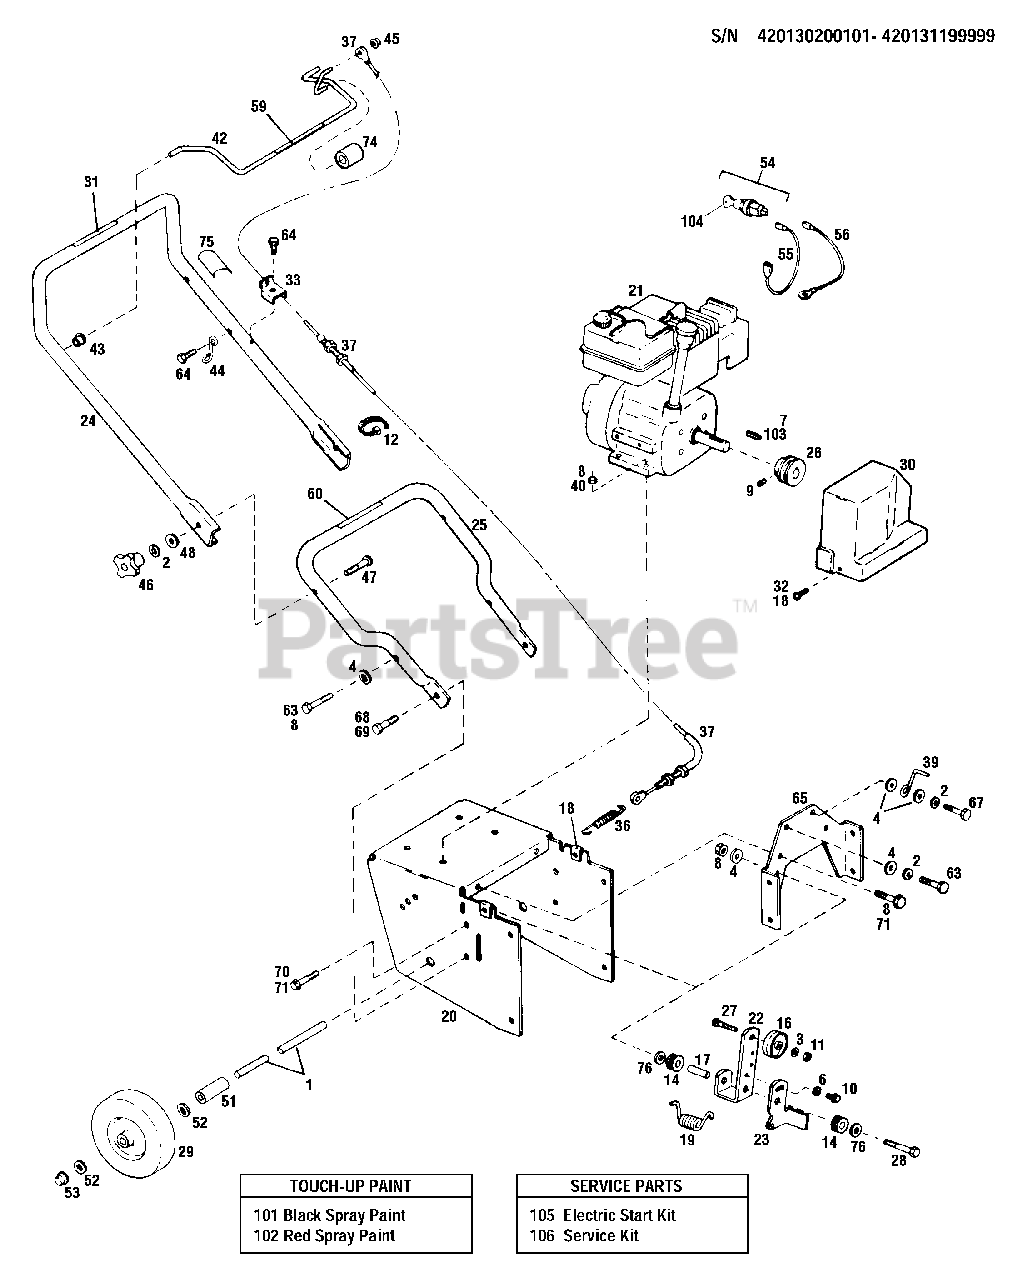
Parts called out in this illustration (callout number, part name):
2	Lockwasher, 5/16
3	Lockwasher, 3/8
4	Flat Washer, 5/16
6	Flat Washer, 1/4
7	Square Key. 3/16 x 3/4
8	Lockout, 5/16-18
9	Set Screw, 5/16-18 x 5/16
10	Thread-forming Screw, 1/4-20 x 1/2
11	Nut. 3/8-16
12	Cable Tie
14	Nyliner Bearing
16	Flat Idler
17	Tubular Spacer
18	U-type Speed Nut, 10-24
19	Torsion Spring
22	Idler Arm
23	Brake Arm
24	Upper Handle Bar
25	Lower Handle Bar
26	Engine Pulley
27	Carriage Bolt 3/8-16 x 1-1/2
28	Bolt 5/16-18 x 2-3/4
29	Wheel and Tire
30	Belt Cover
31	Instruction Decal
32	Round-head Bolt 10-24 x 5/8
33	Control Cable Bracket
36	Extension Spring
37	Cable
39	Belt Guide
40	Bolt 5/16-18 x 1-1/2
42	Contra Lever
43	Flange Bearing
44	Chute Crank Support
45	Push-on Cap
47	Curved-Head Bolt. 5/16-18 x 2
48	Flat Washer, 5/16
51	Spacer
52	Flat Washer, 1/2
53	Push-on Cap, 1/2
54	ignition Switch
55	Wire Lead
56	Ground Lead
59	Auger Control Decal
60	Instruction Decal
63	Bolt, 5/16-18 x 1-1/4
64	Flange Lock Bolt 1/4-20 x 3/4
65	Engine Support
66	Bolt, 5/16-24 x 3/4
67	Bolt, 5/16-24 x 1
68	Flange Lock Boll, 3/8-16 x 3/4
69	Flange Lockout, 3/8-16
70	Flange Lock Boll, 5/16-18 x 1/2
71	Flange Locknut 5/16-18
74	Handle Grip
75	Chute Control Decal
76	Flat Washer. 1/4
101	Black Spray Paint, 13 oz. Can
102	Red Spray Paint 13 oz Can
103	Loctite 242, .02 oz. Tube
104	Ignition Key (key only)
105	Electric Start Kit
106	Service Kit
